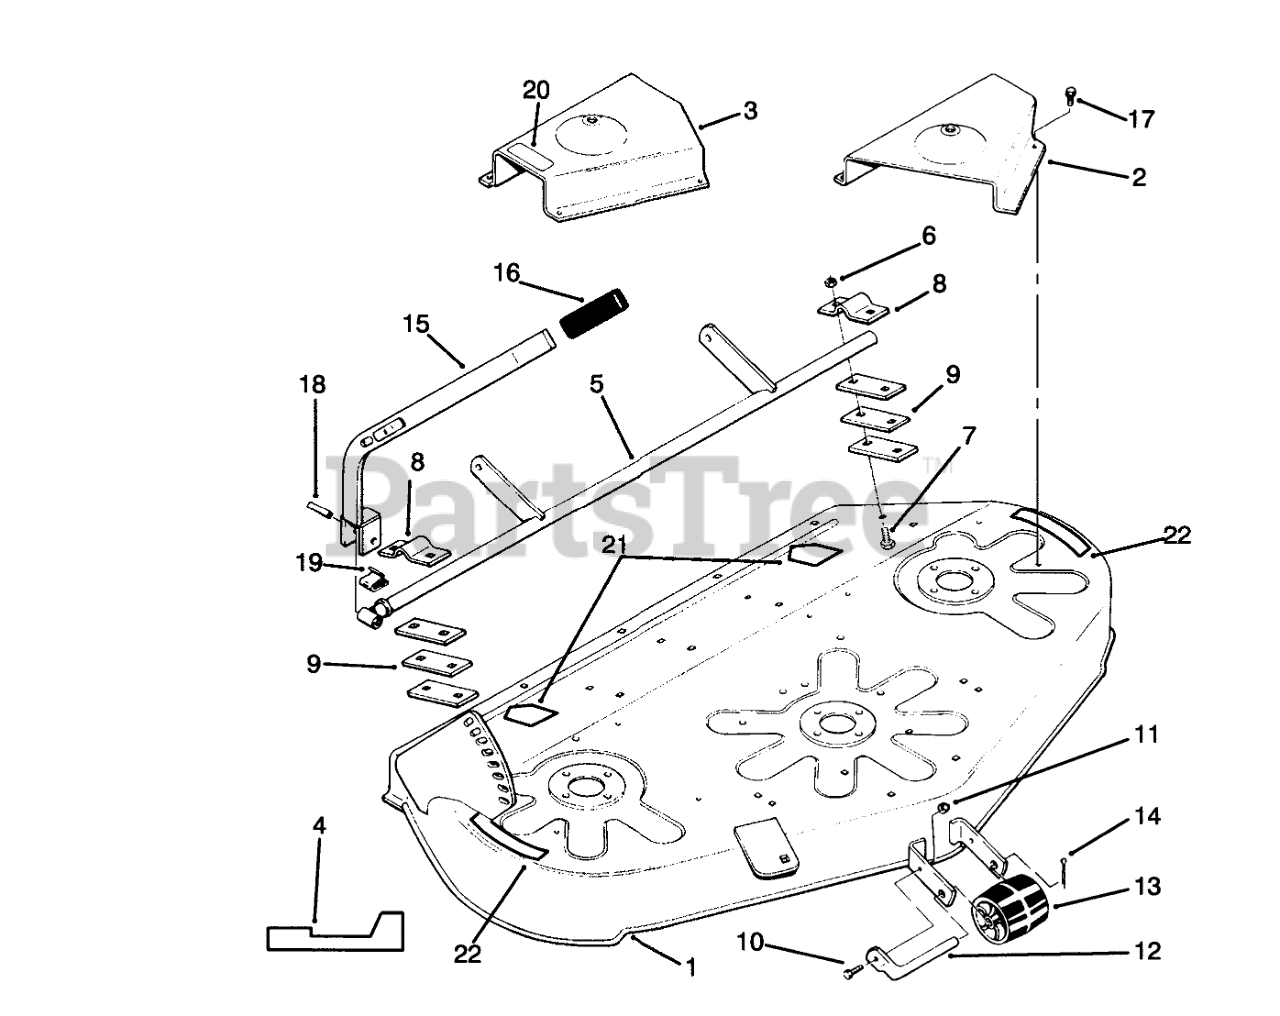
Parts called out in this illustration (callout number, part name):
1	Deck Assembly (Incl. Safety Decals)
2	Belt Cover LH
3	Belt Cover RH
4	DECAL-42" RECYCLER
5	Lift Support
6	NUT-LOCK, NI
7	SCREW-CARR
9	Bar
10	SCREW-HH
11	NUT-LOCK, NI
12	ROLLER-SHAFT
13	Roller
14	PIN-COTTER
15	Lever
17	SCREW-HWH
18	SPIROL PIN 3/8X1 1/2
19	CLIP-SPRING
20	DECAL-HOC
21	DECAL-DANGER
22	DECAL - DANGER
